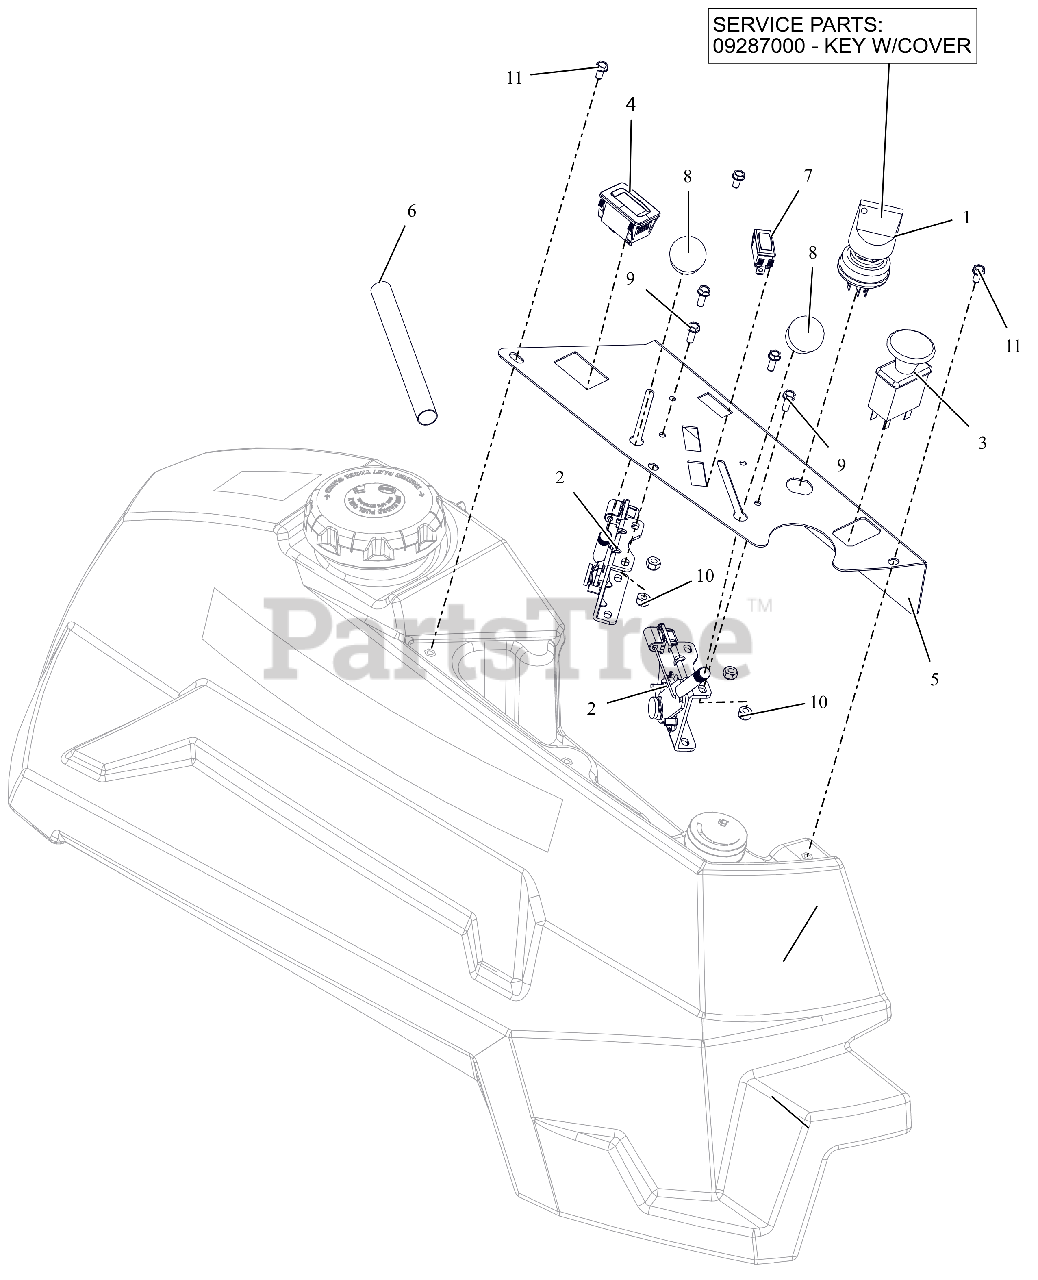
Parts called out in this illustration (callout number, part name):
1	SWITCH, IGNITION
1	KEY, W/ SHIELD
2	CABLE, PRO-CTRL 43.00"
3	SWITCH, CLUTCH
4	HOUR METER
5	PT400 CONTROL PANEL - RED
6	SLEEVE, THERMAL 6"
7	LIGHT, INDICATOR (RED)
8	KNOB-CONTROL-BLACK .38-16X.50
9	BLT, HWH #10-24X.50 ZCC
10	NUT-LK-NYL #10-24 G2 ZCC
11	SCR-MCH 10-24X.38 HWHSTAINLESS
